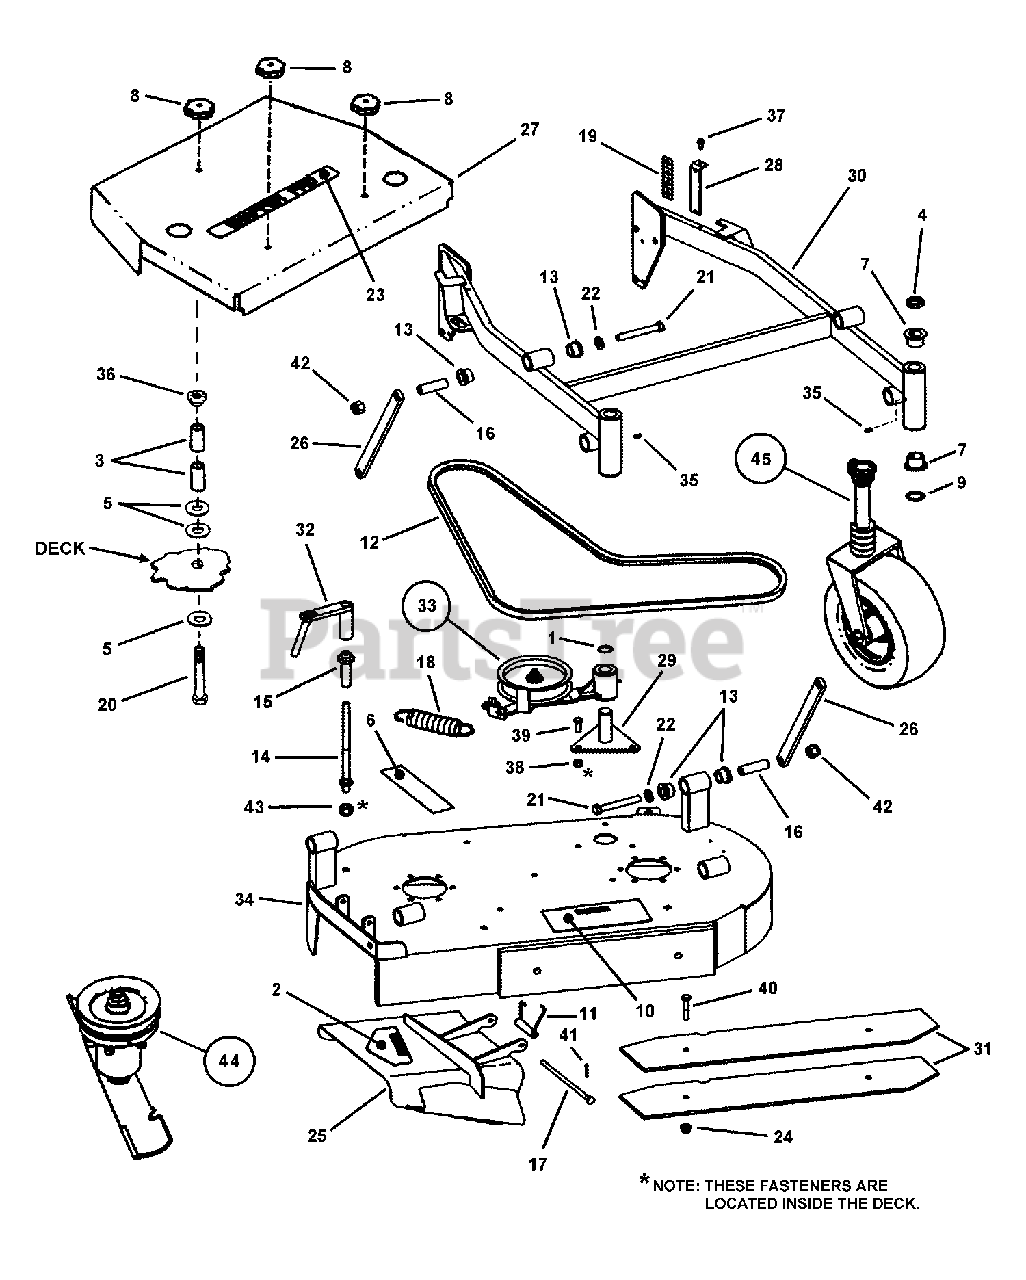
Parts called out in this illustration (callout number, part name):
1	RING, 1" External Retaining
2	DECAL, Warning (CPSC Cut Finger)
3	SPACER
4	SPACER, Powdered Metal
5	WASHER, 3/8" I.D. x 7/8" O.D. x 1/16" Flat
6	DECAL, Danger Guard/Catcher
7	BUSHING, Caster
8	KNOB, Hood (5/16-18 thread)
9	BUSHING, 1"
10	DECAL, Caution- Operator Instruction
11	SPRING, Chute
12	V-BELT, 36" Deck Drive (Nom. Effective Length: 84.80")
13	BUSHING, Suspension
14	STUD, Lift, 1/2-13 Thread, Both Ends
15	LIFT WASHER (Weldment)
16	SLEEVE, Suspension
17	HINGE PIN, Chute
18	SPRING, Idler
19	DECAL, Height of Cut
20	SCREW, 5/16-18 x 4-1/2" Hex Head Cap, GR 5
21	BOLT, 1/2-13 x 3-3/4" Hex Head, GR 5
22	WASHER, 1/2" Flat
23	DECAL, SNAPPER Pro w/Trademark
24	NUT, 3/8-16 Hex Flange Lock
25	DEFLECTOR, 36" ANSI Compliant (Weldment)
26	ARM, Suspension, 12" Long
27	COVER, 36"
28	BRACKET, Height-of-Cut
29	PIVOT, Idler Arm (Weldment)
30	FRAME, 36" Adjustable (Weldment)
31	PLATE, Ballasat
32	ASSEMBLY, Crank
33	ASSEMBLY, Idler Arm, 36"
34	WELDMENT, Deck, Adjustable Height (Red)
35	LUBE FITTING, 1/4-28 Straight
36	NUT, 5/16-18 Hex Flange Lock, GR 5
37	SCREW, 1/4-20 x 5/8" Hex Washer Self-Tap
38	NUT, 3/8-16 HEX NYLON LOCK
39	BOLT, 3/8-16 X 1" GD5 CZ
40	BOLT, 3/8-16 X 2, GD5, CZ
41	COTTER PIN, 3/32 x 1"
42	NUT, 1/2-13 Hex Nyloc
43	NUT, 1/2-13 HEX SIDE LOCK
44	ASSEMBLY, Spindle
45	ASSEMBLY, Caster (Red)
